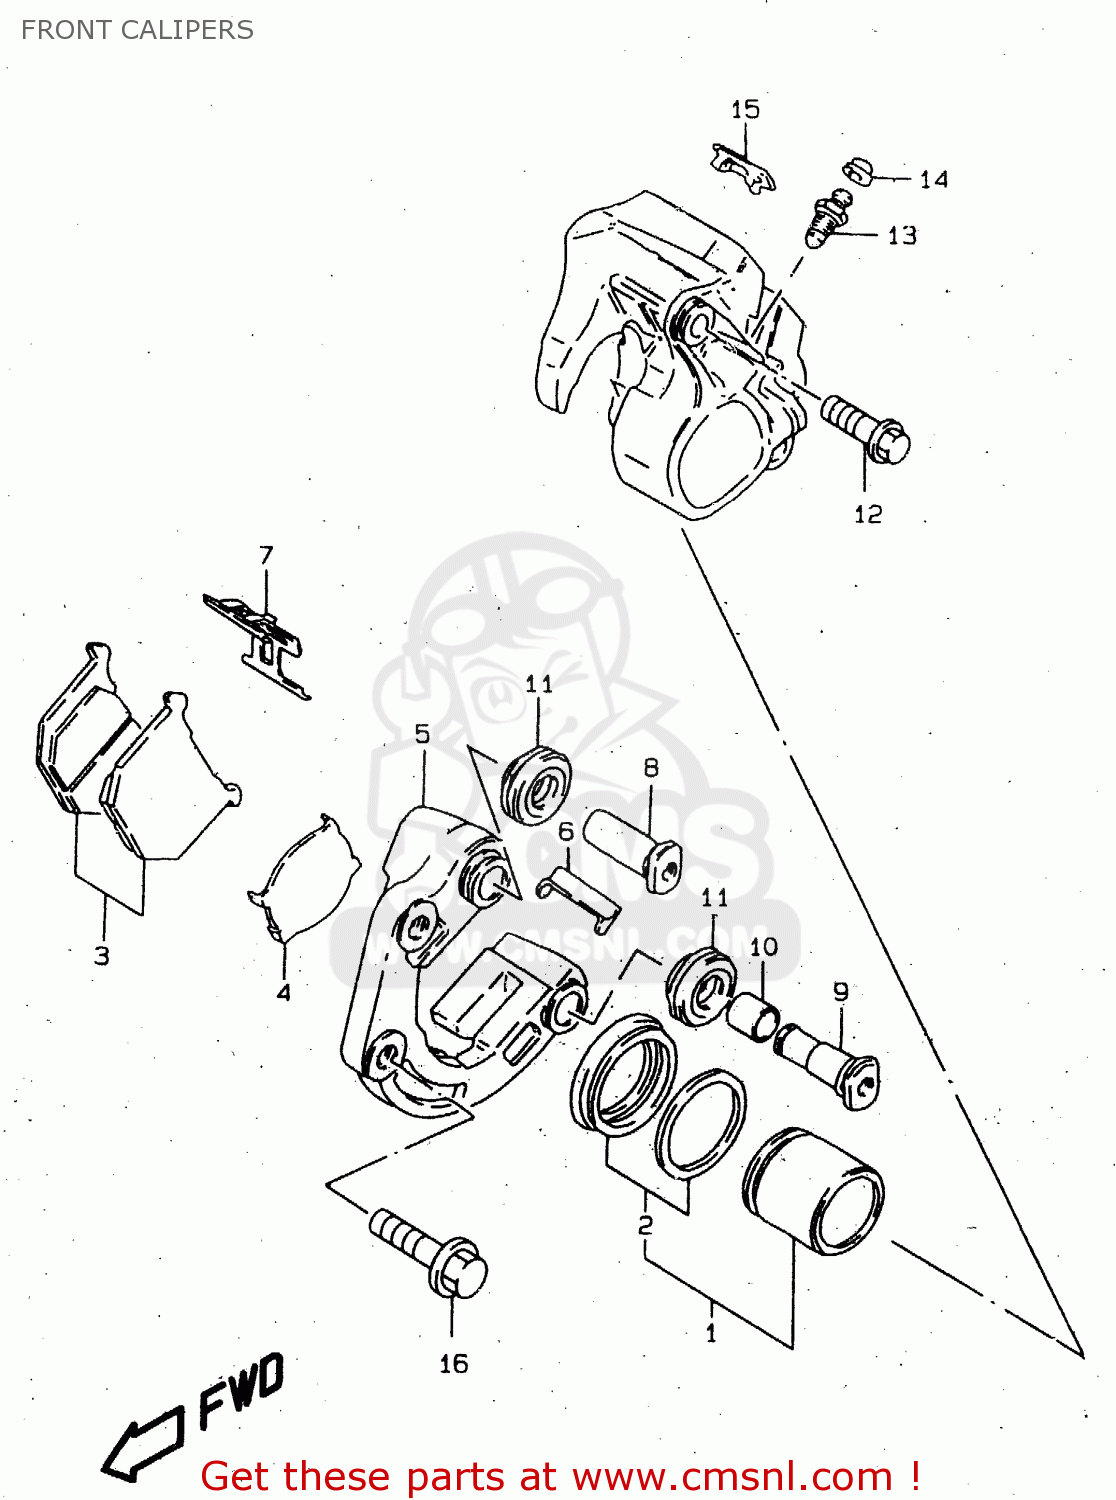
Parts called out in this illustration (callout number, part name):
1	PISTON SET
2	SEAL SET, PISTON
3	PAD SET (NAS)
4	SHIM,PAD
5	CALIPER SET,CARRIER,L
6	GUIDE,PAD
7	SPRING,PAD
8	AXLE NO.1
9	AXLE NO.2
10	BUSH,AXLE
11	BOOT,AXLE
12	BOLT
13	BLEEDER
14	CAP,BLEEDER PLUG
15	COVER
16	BOLT
